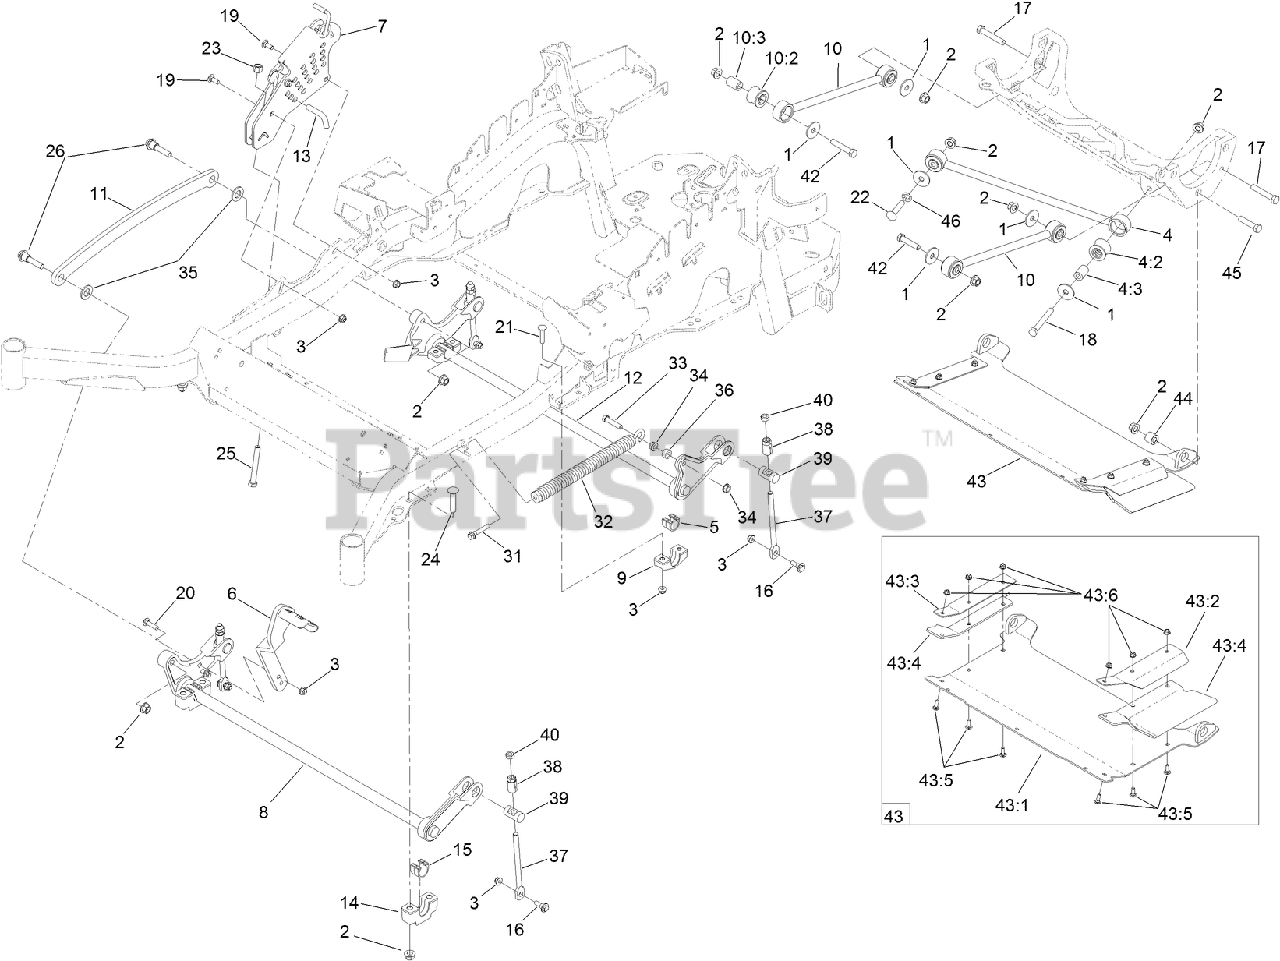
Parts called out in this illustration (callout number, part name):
1	WASHER-THRUST
2	NUT-LOCK
3	NUT-HF, NI
4	PANHARD ROD ASM
4:2	BUSHING-SUSPENSION, RUBBER
4:3	SPACER
5	BEARING-CROSS SHAFT, REAR
6	LEVER-FOOT
7	HEIGHT-OF-CUT ASM
8	DECKLIFT-FRONT
9	SUPPORT-CROSS SHAFT, REAR BEARING
10	DECK STRUT ASM
10:2	BUSHING-SUSPENSION, RUBBER
10:3	SPACER
11	LINK-LIFT, DECK
12	LIFT-DECK, REAR
13	PIN-HOC
14	SUPPORT-CROSS SHAFT, BEARING
15	BEARING-CROSS SHAFT, FRONT
16	SCREW-SHOULDER, HHF
17	SCREW-HH
18	SCREW-HH
19	BOLT-CARR
20	SCREW-CARR
21	SCREW-CARR
22	SCREW-CARR
23	NUT-LOCK, NI
24	BOLT-CARR
25	BOLT-TAP
26	SCREW-HHF, SHOULDER
31	BOLT-SHOULDER
32	SPRING-EXTENSION
33	SCREW-HH
34	NUT-HF
35	WASHER-FLAT
36	SPACER
37	LINK-ADJUSTER, DECK LIFT
38	ADJUSTER-LIFT, DECK
39	TRUNNION
40	NUT-JAM
42	SCREW-HH
43	DISCHARGE TUNNEL ASM
43:1	DISCHARGE TUNNEL ASM
43:2	BRACKET-FLAP, LH
43:3	BRACKET-FLAP, RH
43:4	FLAP-RUBBER
43:5	SCREW-CARR
43:6	NUT-HF, NI
44	BUSHING-SLEEVE
45	SCREW-HH
46	NUT-PUSH
